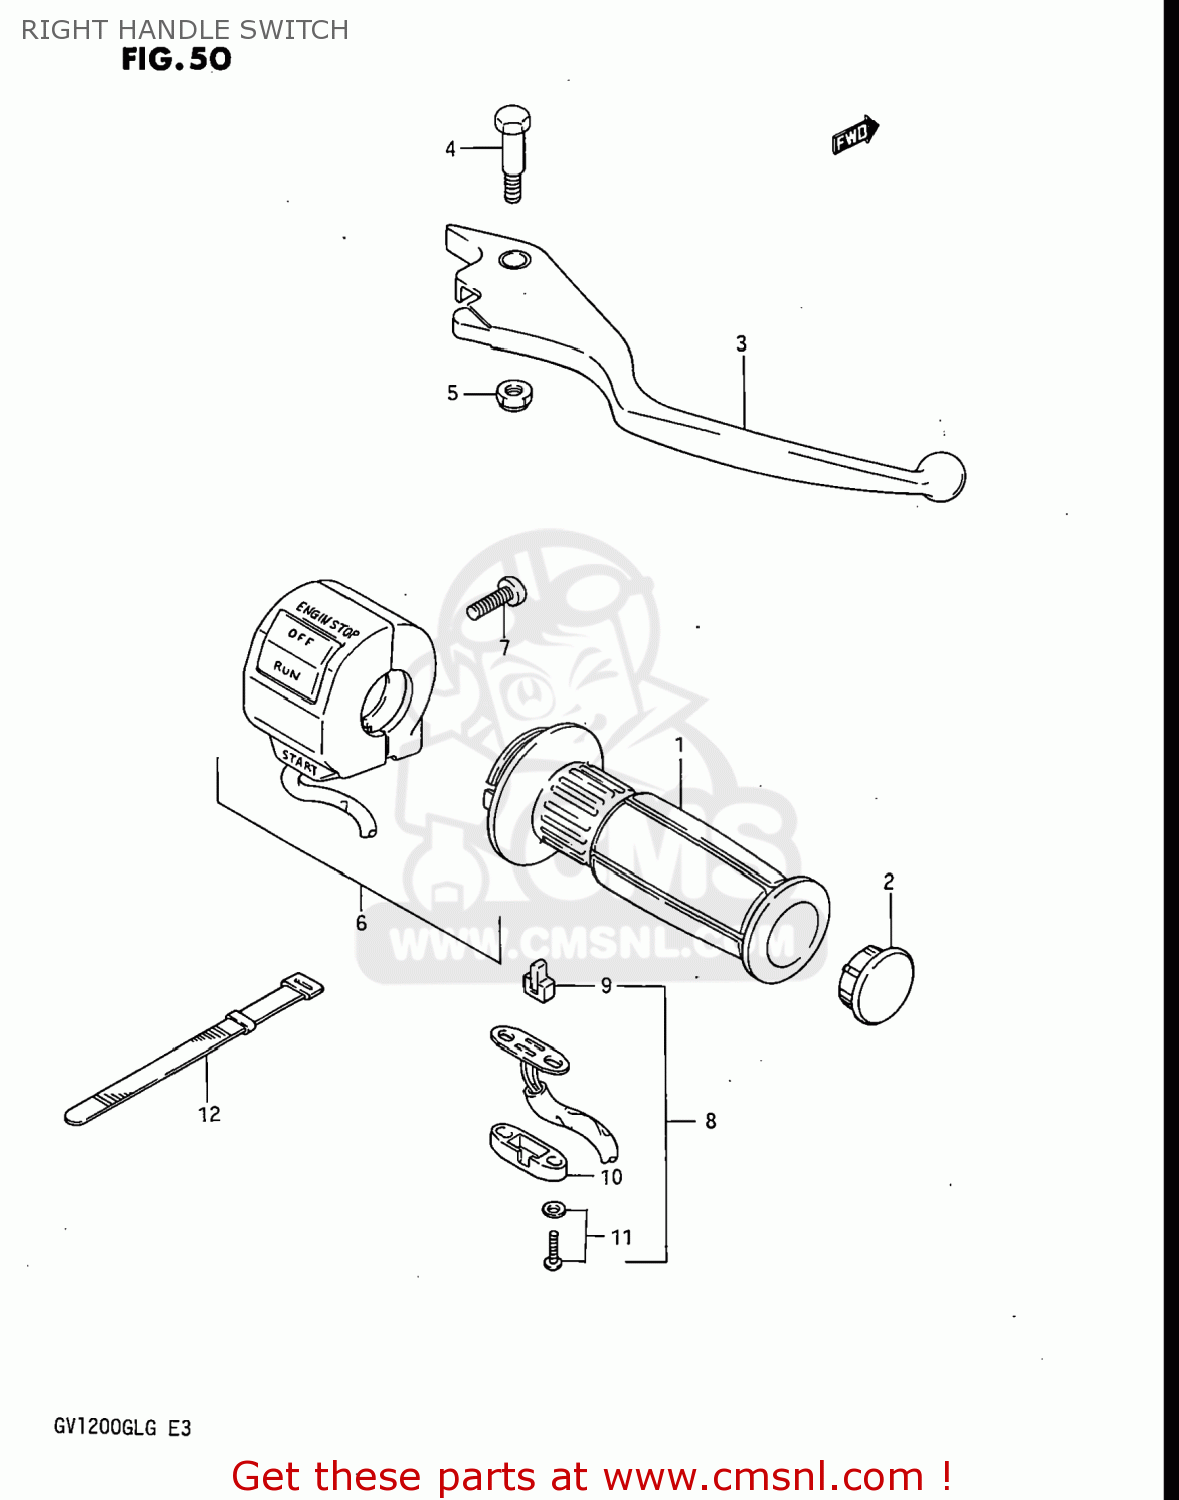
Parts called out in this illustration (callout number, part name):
1	GRIP,THROTTLE
2	CAP,GRIP END
3	LEVER,BRAKE
4	BOLT,LEVER
5	NUT
6	SWITCH ASSY,HANDLE RH
7	SCREW 5X20
8	SWITCH ASSEMBLY
9	CONTACT,SWITCH
10	COVER,FR BK TERMINAL BASE
11	SCREW
12	CLAMP(L:120)
